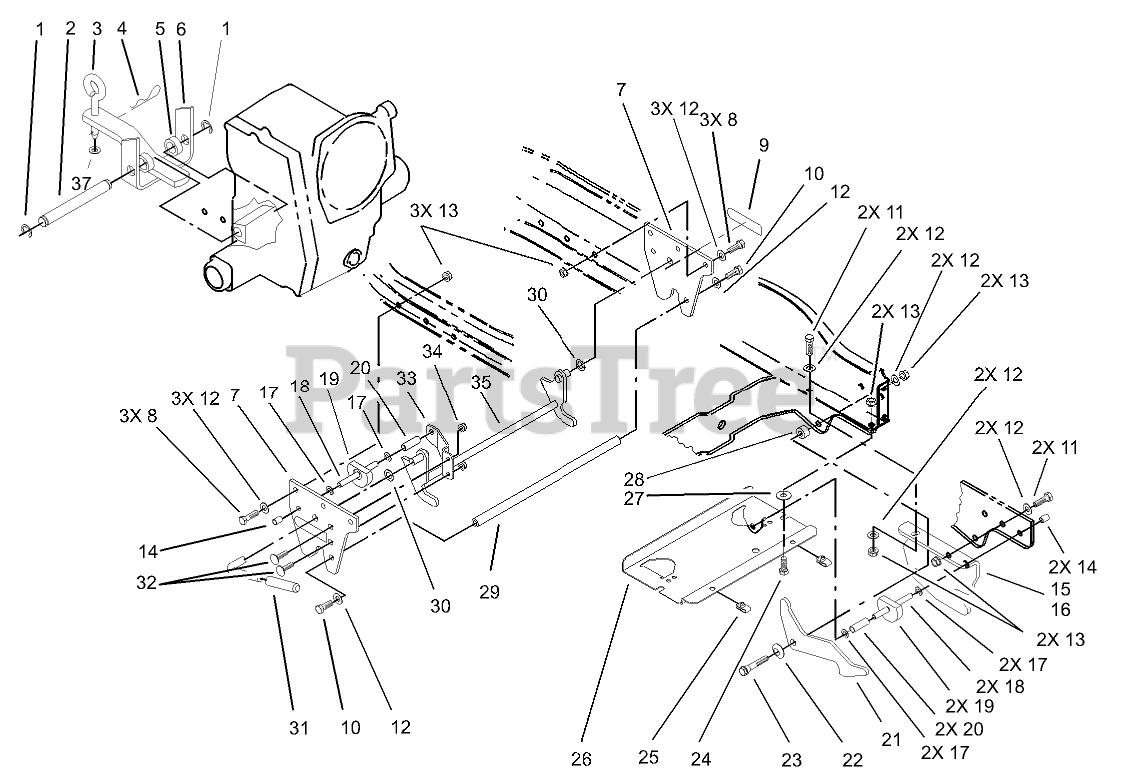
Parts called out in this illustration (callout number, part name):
1	E-RING
2	PIN-STATIONARY HITCH
3	PIN-TOOL
4	PIN-HAIR
5	SPACER
7	PLATE-HITCH
8	SCREW-HH
9	DECAL-ATTACH A MATIC
10	SCREW-HH, LOCK
11	SCREW-HH
12	WASHER-FLAT
13	NUT-LOCK, NI
14	CAP-ROD, PLUNGER
15	HANGER-RH
16	HANGER-LH
17	RING-RETAINING
18	ROD-LOCK
19	LOCK-LATCH
20	SPRING
21	LATCH-BOX, PULLEY
22	WASHER-SPRING
23	BOLT-SHOULDER
24	SCREW-HH
26	TRAY-BATTERY
27	WASHER-TOP THRUST
28	SPACER
29	ROD-SPACER
30	WASHER
31	GRIP
32	BOLT-CARR
33	BRACKET-ARM, MID
34	NUT-LOCK, NI
37	WASHER-FLAT
